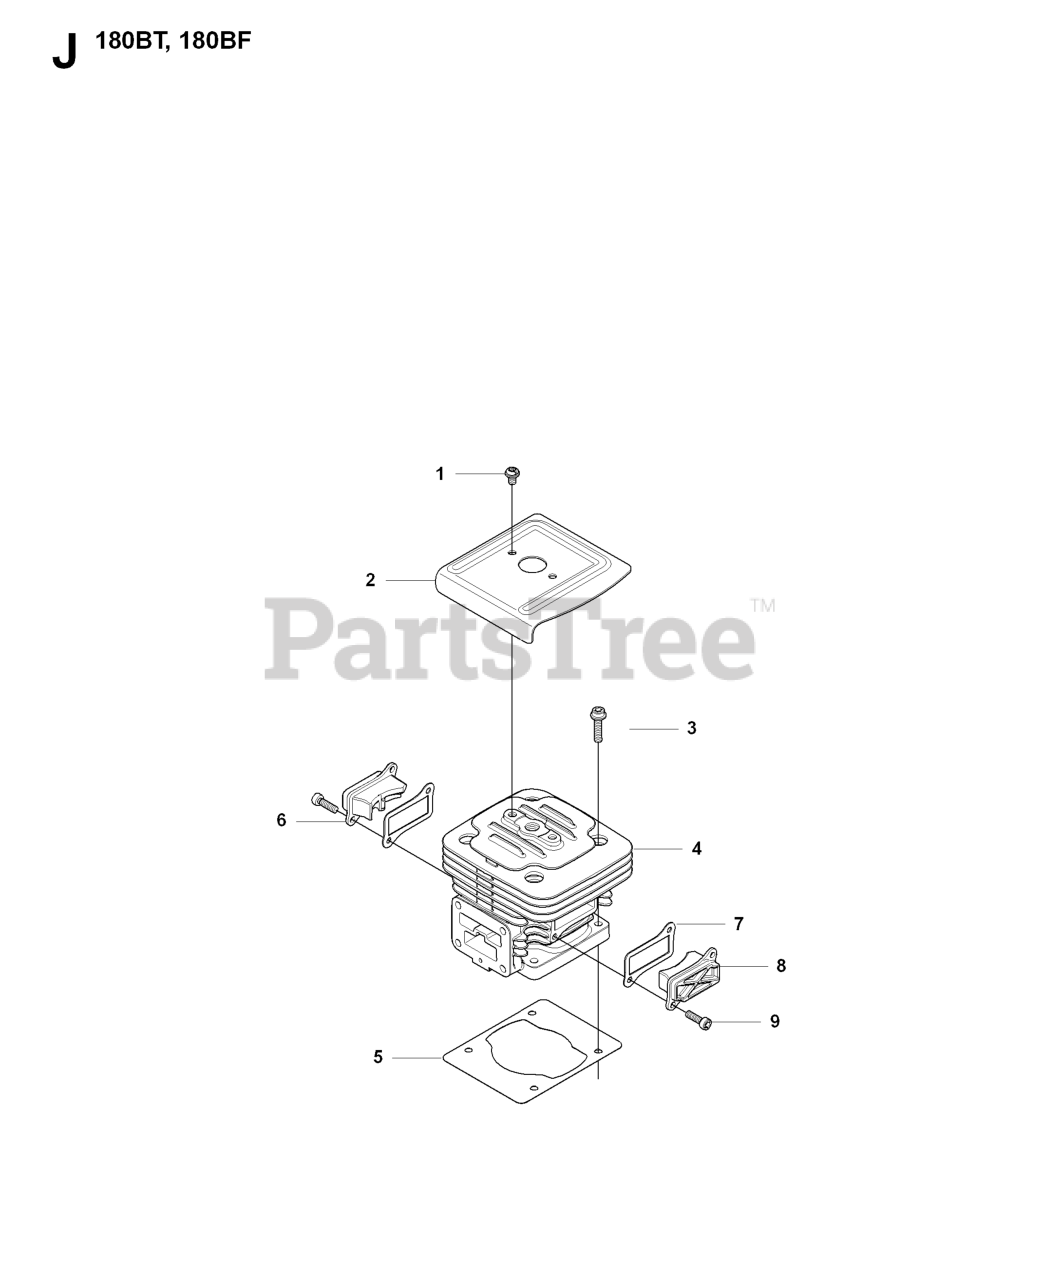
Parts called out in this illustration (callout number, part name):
3	BOLT
5	RP_GASKET
6	COVER TR(F)
7	GASKET
8	COVER TR(S)
9	BOLT
